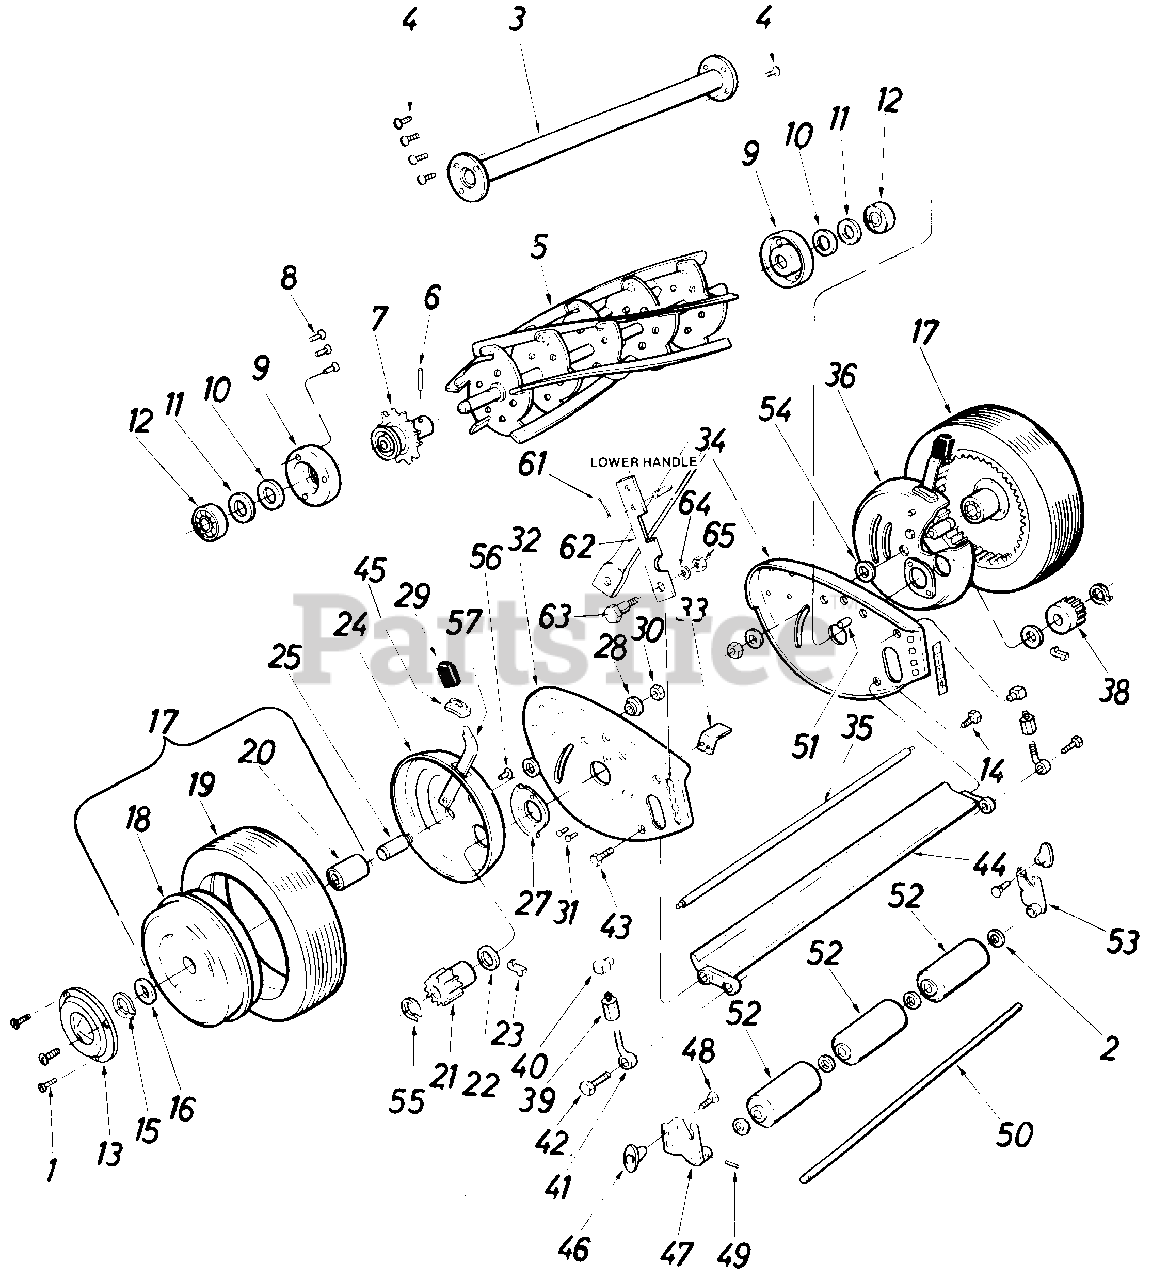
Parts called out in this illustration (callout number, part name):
1	Ph. Hd. Scr. 10-32 x .62" Lg.
2	Roller Washer
3	18" Spacer Tube Ass'y.
4	Rivet 3/16 x 3/8"
5	18" Reel Ass'y.
6	Roll Pin
7	Sprocket Anti-Wind Cup and Hub Ass'y.
8	Rivet 3/16 x 13132"
9	Retainer
10	Felt Washer
11	Felt Retainer
12	Beari ng
13	Hub Cap
14	Scr. Cutter Bar L.H. Thd.
15	Retaining Ring
16	Washer
17	Wheel Ass'y. Comp
18	Wheel Ass'y. w/Bearing
19	Tire
20	Bearing
21	Pinion Gear R.H.
22	Felt Washer
24	Gear Housing L.H.
27	Retainer
28	Bushing
29	Wheel Adj. Knob
30	Hex Lock Nut
31	Hex Sems Scr. 10-32 x .375" Lg.*
32	End Plate w/Trunnions
33	Scraper
34	End Plate w/Trunnions
35	End Plate Spacer
36	Gear Housing
38	Pinion Gear
39	Turnbuckle Nut
40	Trunnion
42	Screw
43	Scr. Cutter Bar R.H. Thd.
44	18" Cutter Bar Ass'y.
45	Dust Cover
46	Roller Adj. Knob
47	Roller Brk't. Ass'y. L.H.
48	Hex Scr. 5/16-18 x .62" Lg.
49	Roll Pin
50	Roller Shaft
51	Trunnion
52	Roller
53	Roller Brk't. Ass'y. R.H.
54	Washer
55	Retaining Ring
56	Hex Scr. #10-32 x .375" Lg.
61	Internal Cotter Pin
62	Handle Brace
63	Shld. Bolt 5/16-18 Thd.
64	L-Wash. 5/16" Scr.
65	Hex Nut 5/16-18 Thd.
